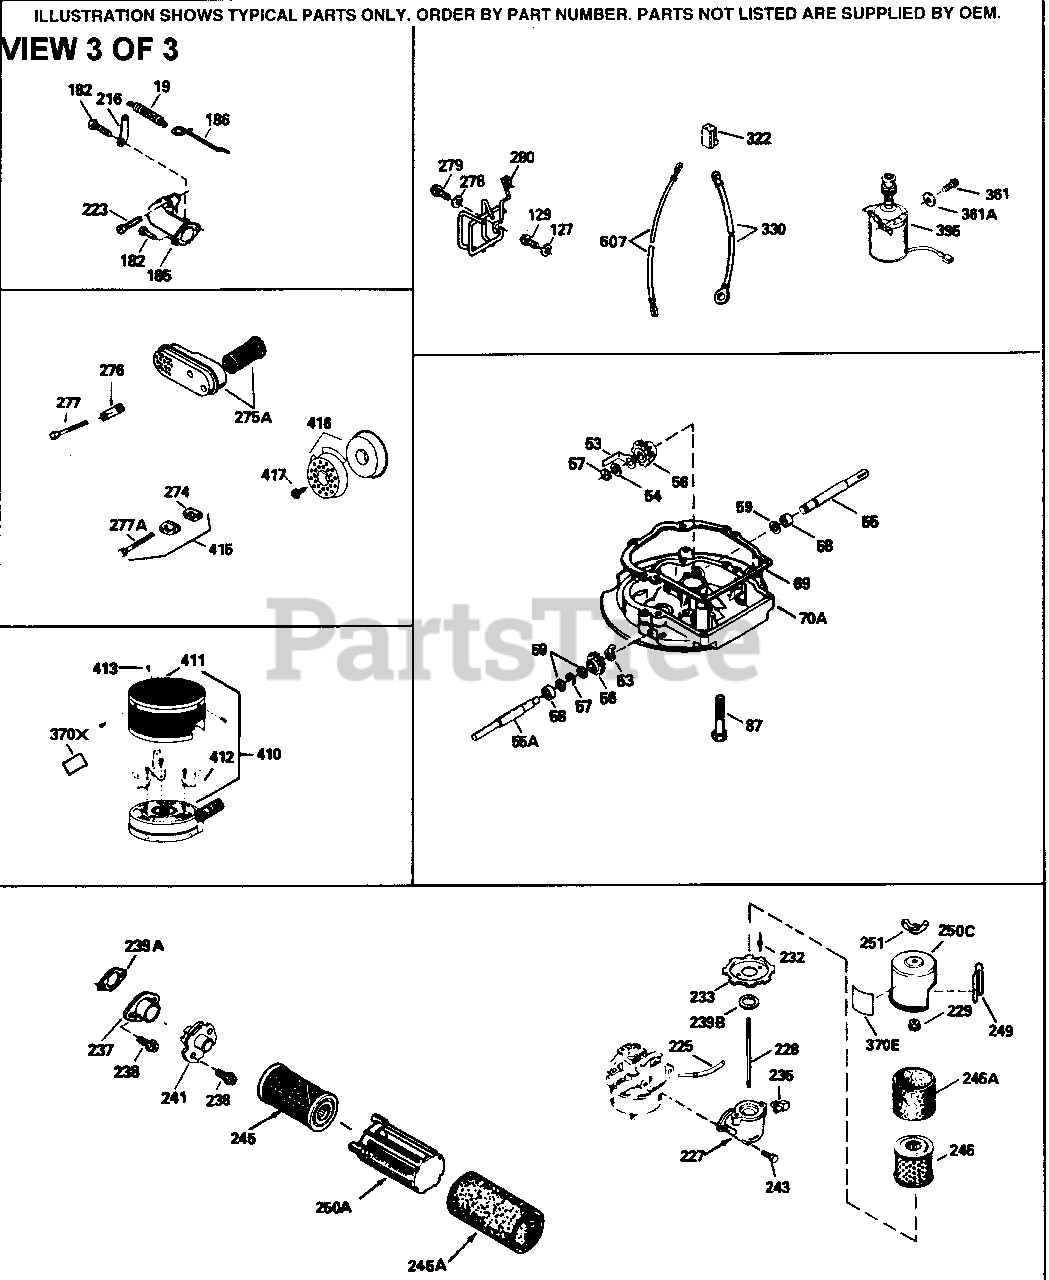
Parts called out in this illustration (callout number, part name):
19	Extension Spring
69	* Mounting Flange Gasket
182	Screw, 1/4-28 x 7/8"
185	Intake Pipe (Incl. 224)
186	Governor Link
223	Screw, 1/4-20 x 1"
227	Air Cleaner Elbow Ass'y Incl. 235 &24 3
228	Stud, 1/4-20 x 6.2"
229	Nut & Lockwasher, 1/4-20
233	Air Cleaner Base
235	Air Cleaner Elbow Fitting
238	Screw, 10-32 x 3/4"
239A	Air Filter Gasket
239B	Air Cleaner Gasket
245	Air Filter
245A	Air Filter
249	Air Cleaner Cover Seal
251	Wing Nut
275A	Muffler (Incl. 277)
276	Locking Plate
277	Screw, 1/4-20 x 2-1/4"
305	Oil Fill Tube
322	Connector Body
330	Wire Harness One female fitting & one eyelet
330	Wire Harness (3-wire)
370E	Air Cleaner Decal
